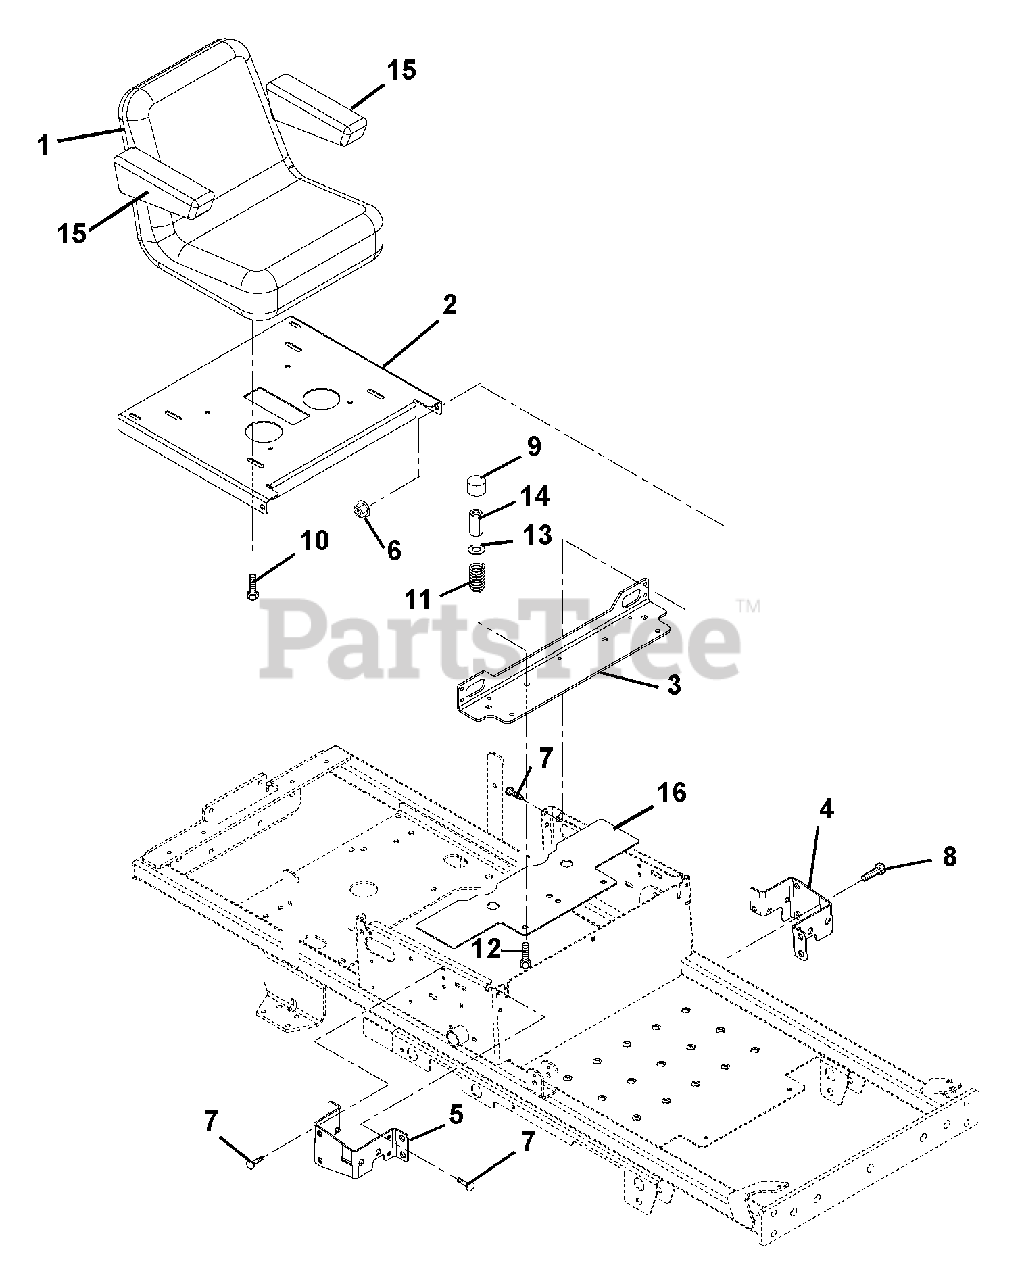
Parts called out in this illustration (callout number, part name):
1	Seat with Arm
2	Seat Plate
3	Bracket, Seat Spring
4	Bracket, RH Steering Stop
5	Bracket, LH Steering Stop
6	Nut, Locking Flange .38-16
7	Screw, Tapping .31-18 x .50
8	Bolt, Shoulder .375-16 x 1.50
10	Bolt-Hex .31-18 x 1.00 Grade 5
11	Spring, Seat
12	Bolt, Round Head Square Neck .31-18 x 1.50 Grade 5
13	Washer-Flat-Steel .328 x .87 x .179
14	Nut, Coupling 5/16-18 x 1 .75
15	Arm Rest
16	Guard, HVZ Finger
